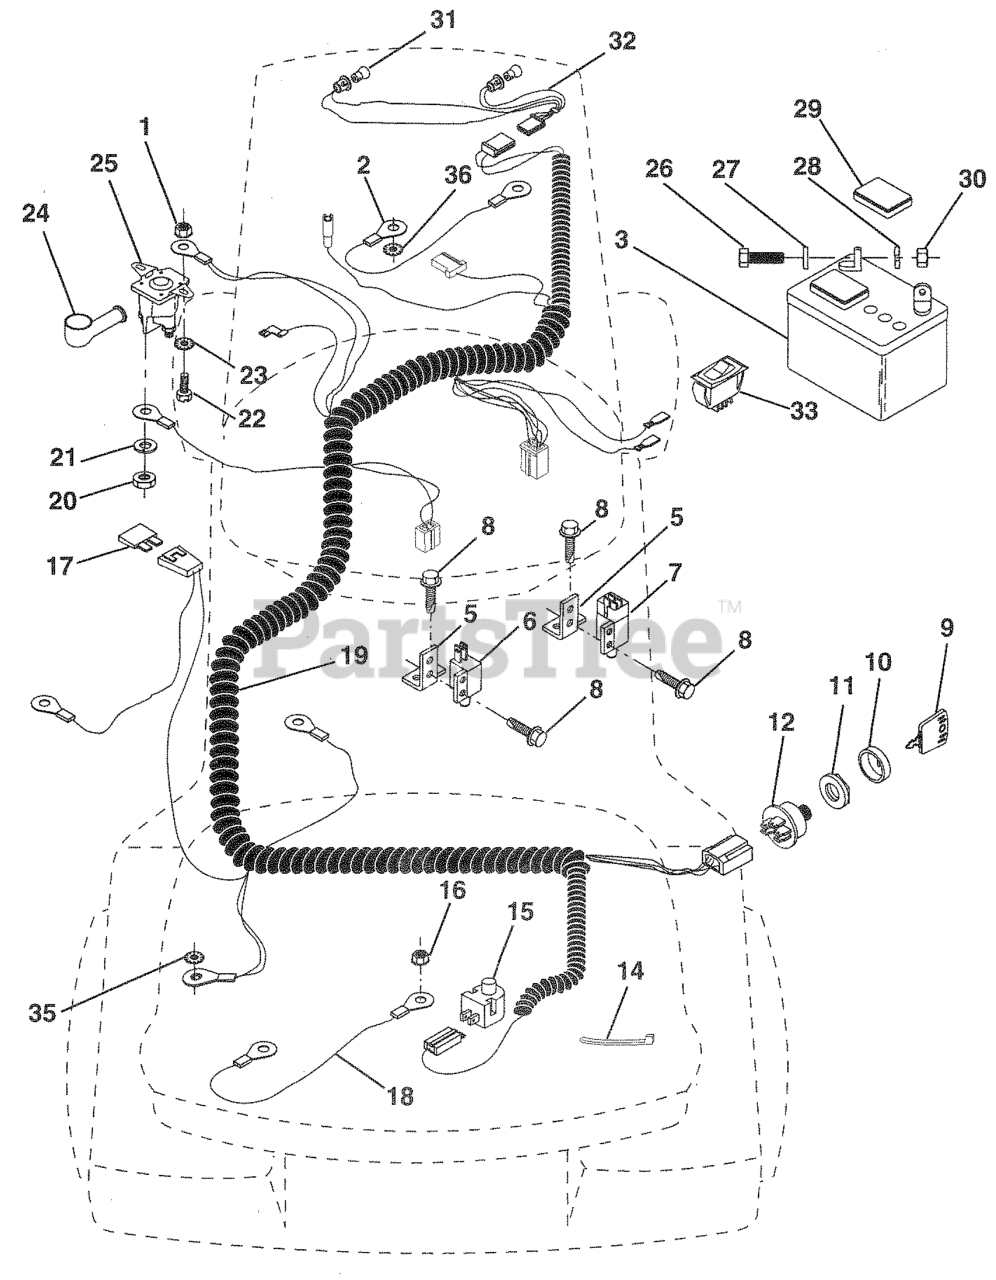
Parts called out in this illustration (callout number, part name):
1	NUT
2	CABLE ASSY
3	BATTERY
5	BRACKET LT
6	SWITCH-INTER. GT
7	SWITCH INTERLOCKT
9	KEY.MOLDED.GENERIC
10	COVER KEY IGNITIO
11	NUT IGNITION
12	SWITCH
14	TIE GUIDE
15	RP.SWITCH.PLUNGER.NC.GRAY
16	NUT
18	CABLE.BATTERY.6GA.16"RED
19	IGNITION HARNESS
20	NUT
21	LOCKWASHER
22	BOLT
23	Washer, Lock Ext. Tooth 1/4
24	TERMINAL COVER
25	SOLENOID
26	BOLT.HEX.1/4.X.3/4.DICHROMATE
27	WASHER
28	LOCKWASHER
29	CAP BATTERY NLA
30	NUT
32	SOCKET LIGHT HARNESS
35	Lockwasher Int. Tooth 1/4
